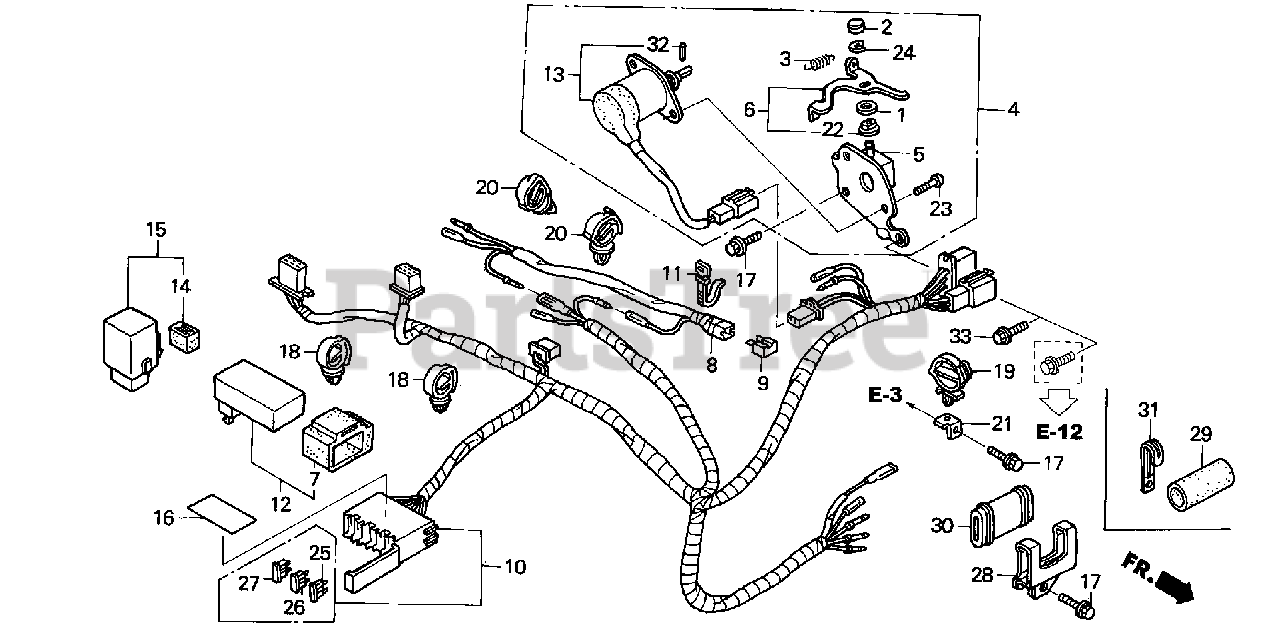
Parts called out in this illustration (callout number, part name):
2	CAP, CHOKE LEVER
3	SPRING, CHOKE RETURN
4	AUTO-THROTTLE ASSY.
5	STAY, SOLENOID THROTTLE
6	LEVER, SOLENOID THROTTLE
7	CUSHION, IGNITION CONTROL MODULE (CDI)
8	DIODE ASSY., SOLENOID
9	RECTIFIER, SILICON
10	SUB-WIRE HARNESS ASSY.
11	BAND B1, WIRE
12	CONTROL UNIT, SOLENOID
13	SOLENOID ASSY.
14	SUSPENSION, TURN SIGNAL RELAY (MITSUBA)
15	TIMER UNIT
16	LABEL, FUSE
17	BOLT, FLANGE (6X12) (CT200)
18	CLIP, WIRE HARNESS (25MM)
19	STRAP, WIRE HARNESS (25MM) (BLACK)
20	CLIP, HARNESS
21	BASE, CORD CLIP
22	BUSH, AUTO-THROTTLE LEVER
23	SCREW, PAN (5X8)
24	E-RING (4MM)
25	FUSE, BLADE (5A)
26	FUSE, BLADE (5A)
27	FUSE, BLADE (10A)
28	CLIP, WIRE
29	TUBE, CORD
30	TUBE, CORD
31	CLIP, WIRE HARNESS
32	PIN, SPRING (2X6)
